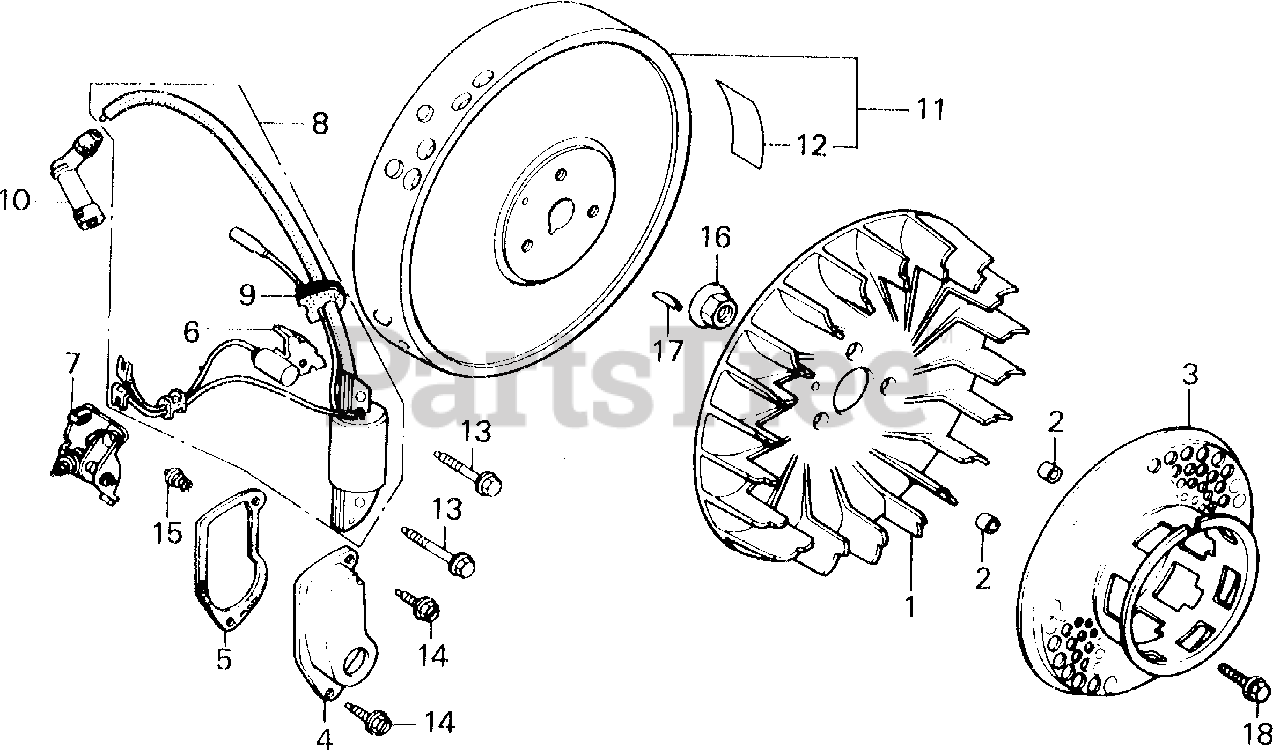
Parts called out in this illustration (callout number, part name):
1	FAN, COOLING
2	COLLAR, FAN
3	PULLEY, STARTER
4	COVER, POINTS
5	GASKET, POINT COVER
6	CONDENSER
7	POINTS ASSY.
8	COIL ASSY., IGNITION
9	GROMMET, WIRE
10	CAP ASSY., NOISE SUPPRESSOR
11	FLYWHEEL (POINT)
12	MARK, FLYWHEEL CAUTION
13	BOLT, FLANGE (6X32)
14	BOLT, FLANGE (5X10)
15	SCREW-WASHER (5X12)
16	NUT, SPECIAL (14MM)
17	KEY, SPECIAL WOODRUFF (25X18)
18	BOLT, FLANGE (6X16)
